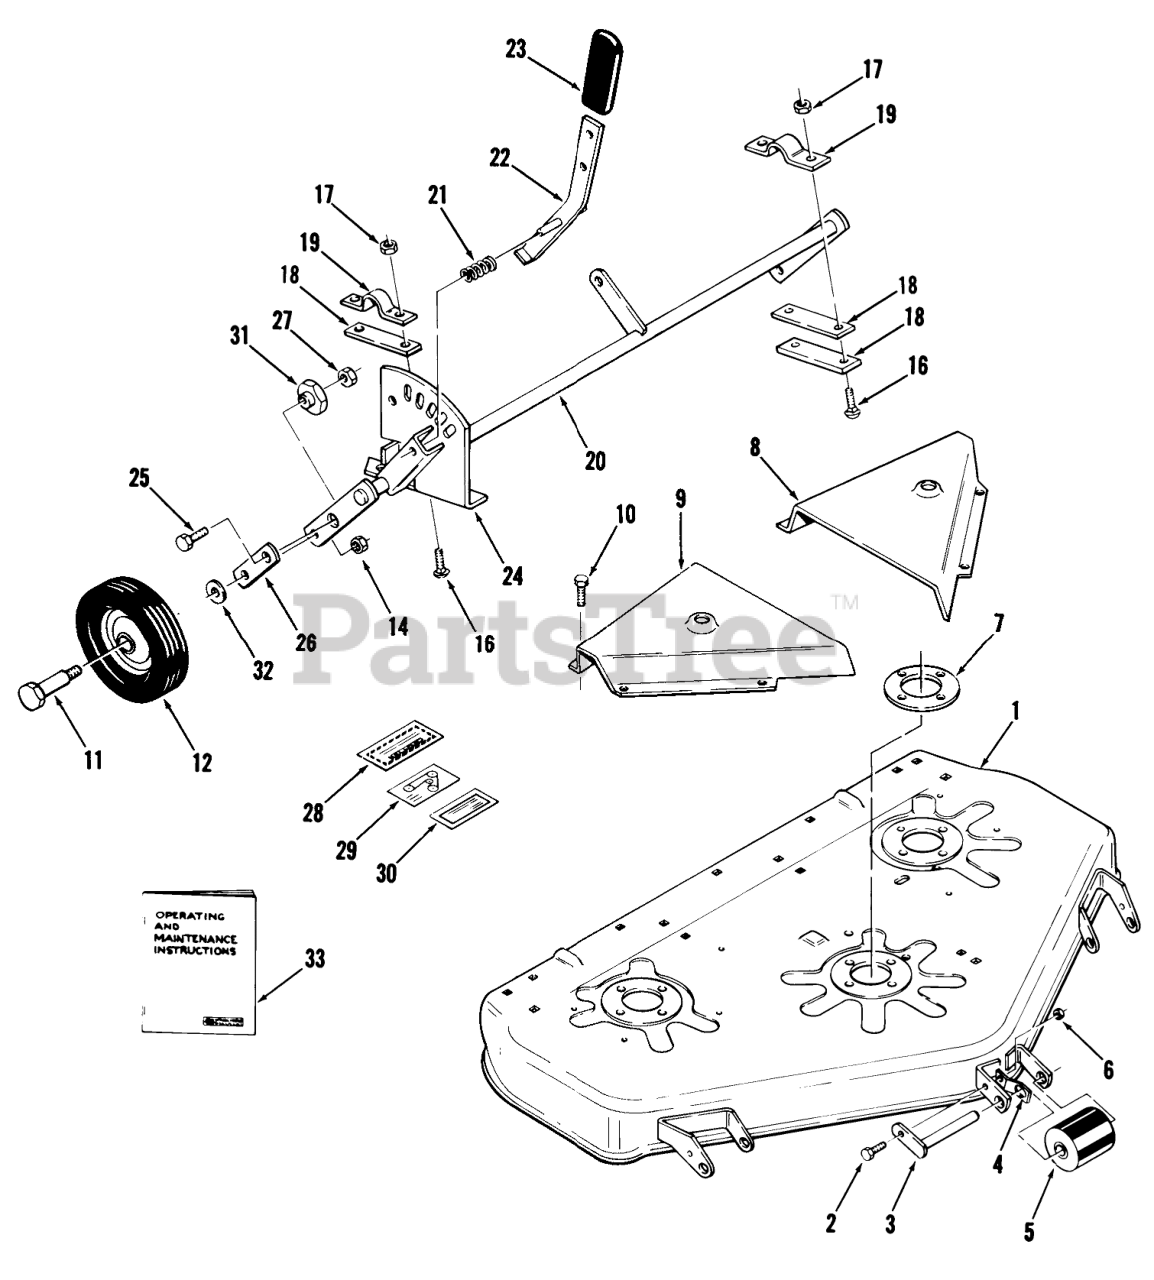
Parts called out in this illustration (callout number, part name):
1	Mower Deck
2	H H C S
3	Roller Shaft
4	SPRING ROLLER STOP
5	Roller
6	Nut
7	PLATE-SPINDLE
8	Belt Cover LH
9	Belt Cover RH
10	Bolt
11	BOLT-SHOULDER
12	Wheel 6 x 1.75 (w/5306 Bushings)
14	Nut
16	Bolt
17	Nut
18	Strap
19	CLAMP
20	Gage Wheel Support
21	SPRING-COMPRESSION
22	Lever
24	Quadrant
25	Bolt
26	Wheel Plate
27	Nut
28	Caution Decal
29	DECAL-HEIGHT & BELT
30	Decal-Caution
31	STEERING ARM
32	WASHER
33	Operating and Maintenance Instructions
